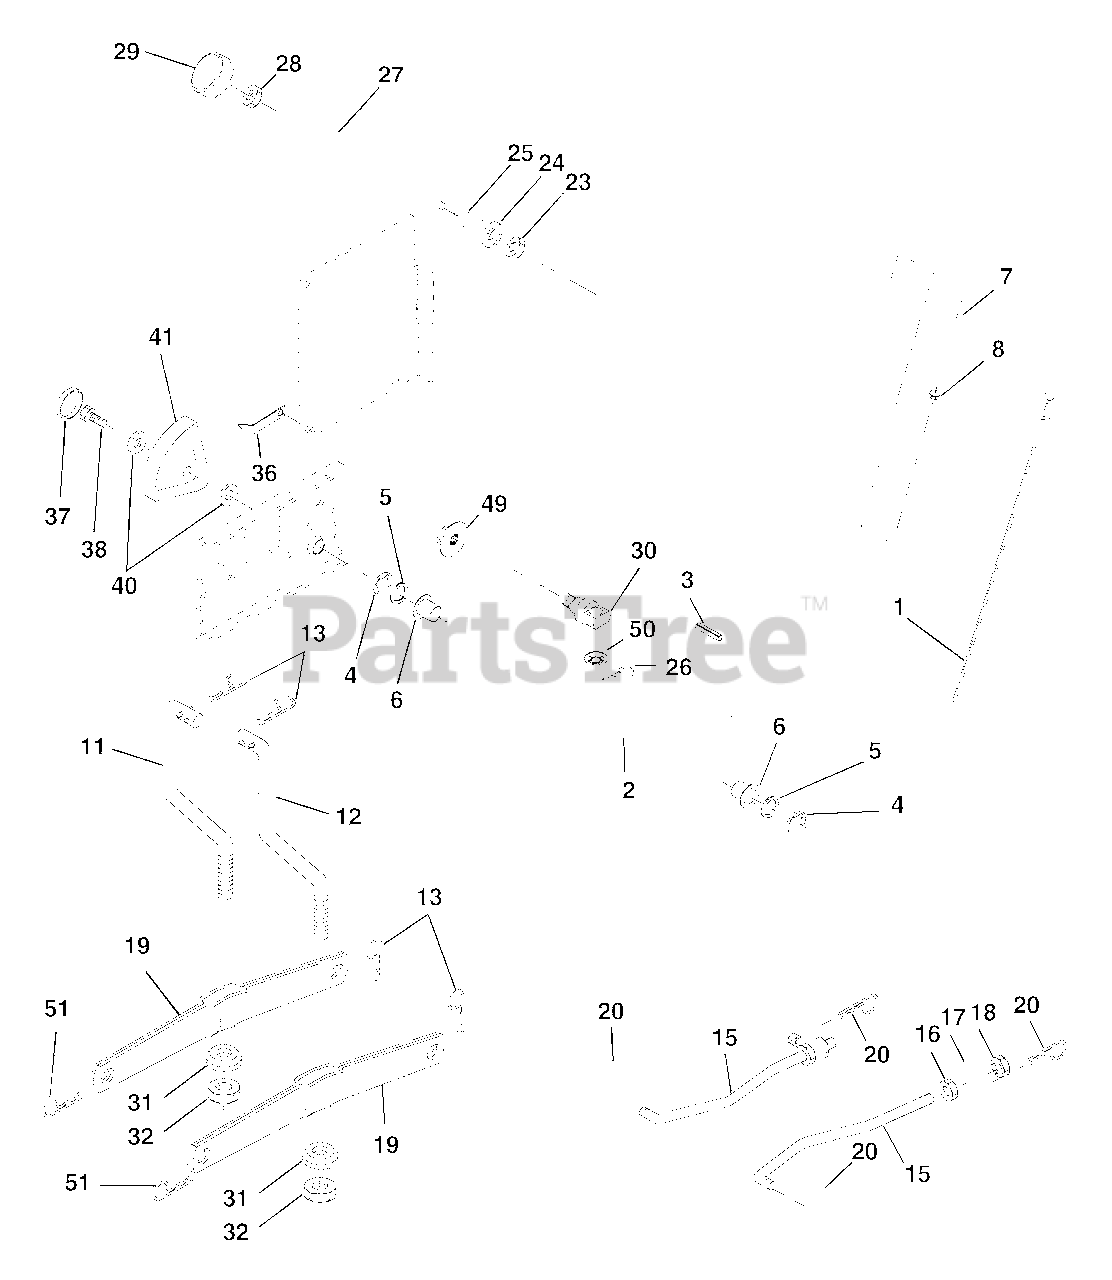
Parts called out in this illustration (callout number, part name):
1	Washer Asm Inner Spring W/Plunger
2	Shaft Asm. Lift
3	Pin Groove
4	E Ring #5133-62
5	Washer 21/32 x 1 x 21 Ga.
6	Bearing Nylon
7	Grip Handle
8	Button Plunger Black
11	Link Asm Lift L.H.
12	Link Asm Lift R.H.
13	Retainer Spring
15	Link Front
16	Nut Jam Hex 1/2-13 Unc
17	Trunnion Blk Zinc
18	Nut Lock W/Wsh 1/2-13 Unc
19	Arm Suspension Mower
20	Retainer Spring
23	Nut Special
24	Washer 13/32 x 5/8 x 16 Ga.
25	Spring 2-1/8
26	Retainer Clip
27	Rod Adj Lift Zinc
28	Nut Hex Jam 3/8-16 Unc
29	Knob Inf 3/8-16 unc
30	Trunnion Infin Height
31	Bearing, Pvt. Lift. Spherical
32	Nut Crownlock 3/8-24
36	Pointer Height Indicator
37	Plug Hole Blk
38	Screw 5/16-18 x 1
40	Washer 11/32 x 1-1/2 x 10 Ga
41	Scale Ind Height Blk
49	Nut Hex flange lock
50	Nut Push Phos & Oil
51	Retainer Spring
